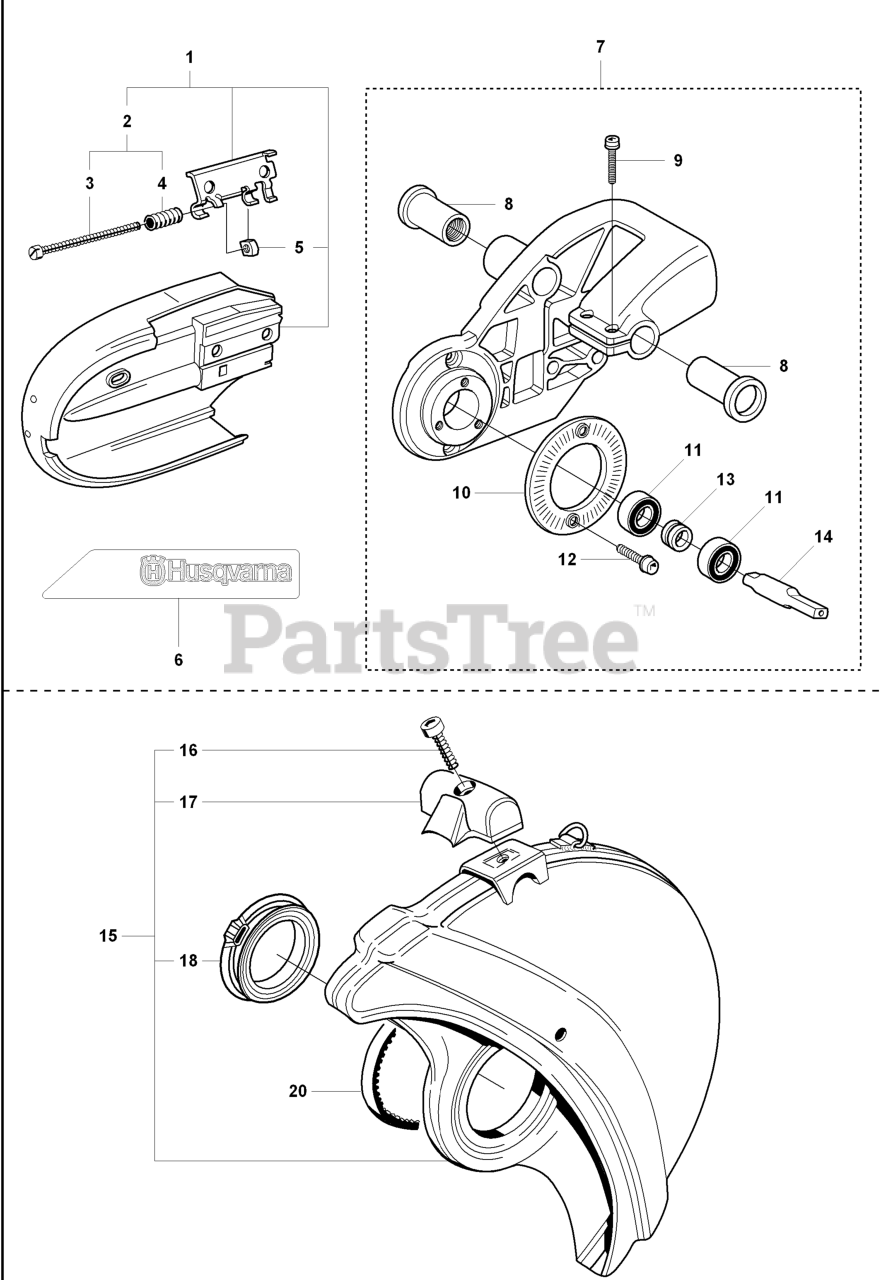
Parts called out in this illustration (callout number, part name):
1	BELT GUARD
1	PROTECTOR
2	TENSIONER
7	BEARING HOUSING
11	BALL BEARING
15	RP GUARD
15	PROTECTOR
16	SCREW MC6S 5X20
19	V-BELT
